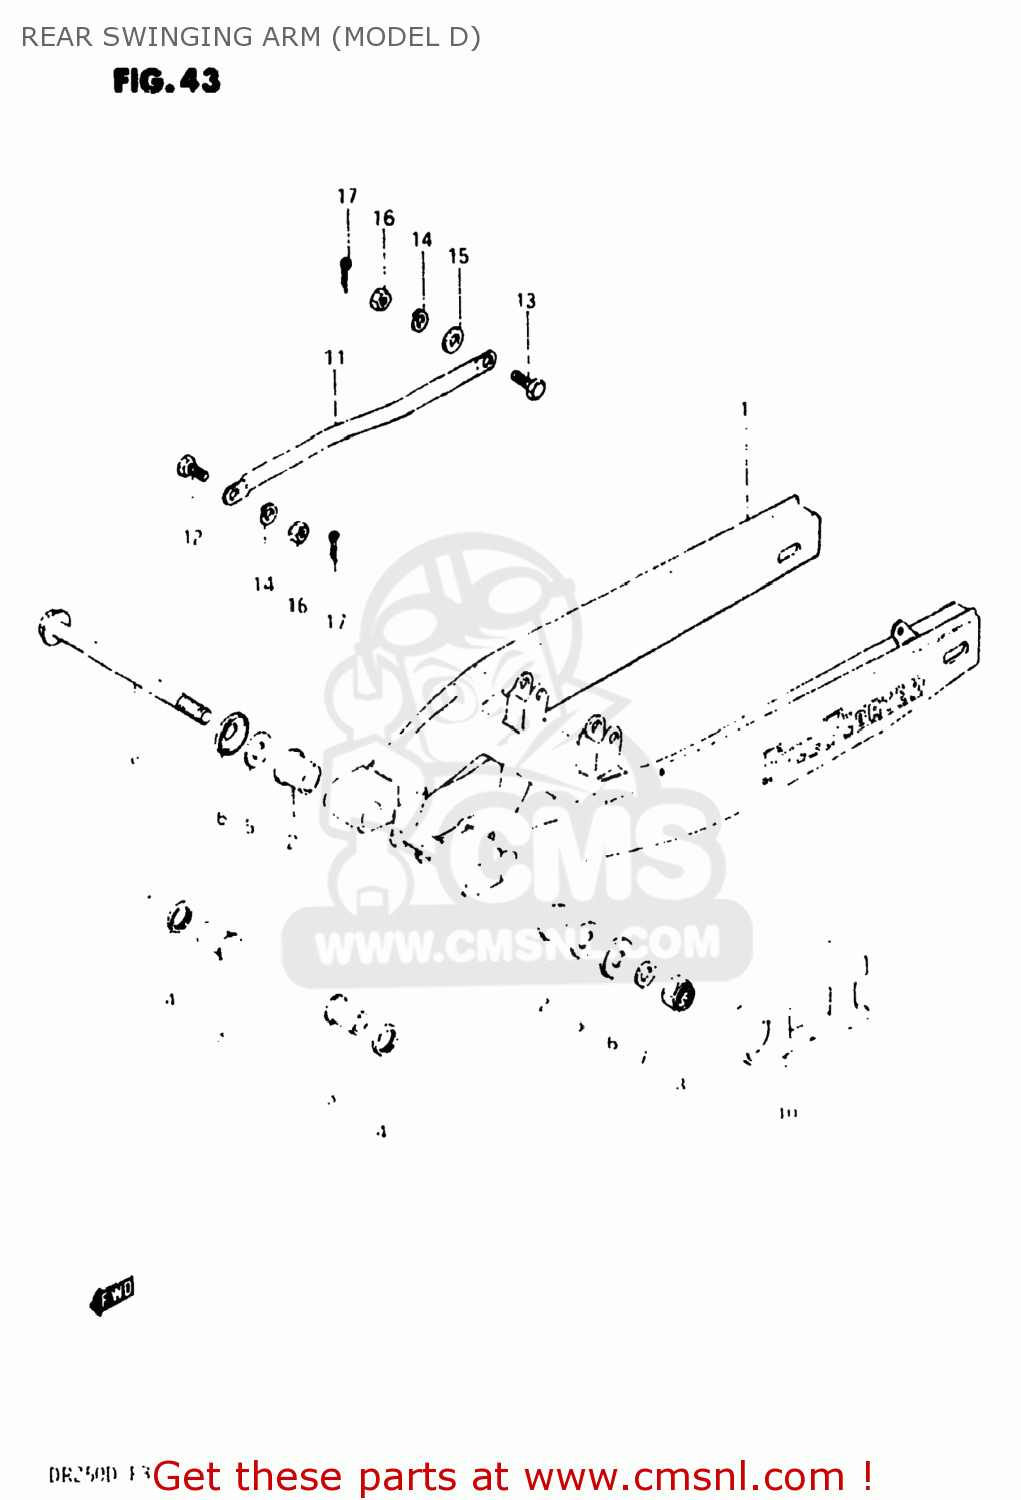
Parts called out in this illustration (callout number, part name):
1	SWING ARM ASSEMBLY,REAR
2	BUSHING,RR SWGARM PIVOT
3	SPACER,RR SWGARM PIVOT OUTER
4	SEAL,OIL(20X27X5)
5	WASHER
6	COVER,REAR SWING ARM DUST
7	WASHER
8	NUT 14MM
9	SHAFT,REAR SWING ARM
10	BUFFER,CHAIN TOUCH DEFLECTOR
11	LINK,REAR TORQUE
12	BOLT
13	BOLT(8X26.5)
14	LOCK WASHER
15	WASHER
16	NUT
17	PIN 20X20
